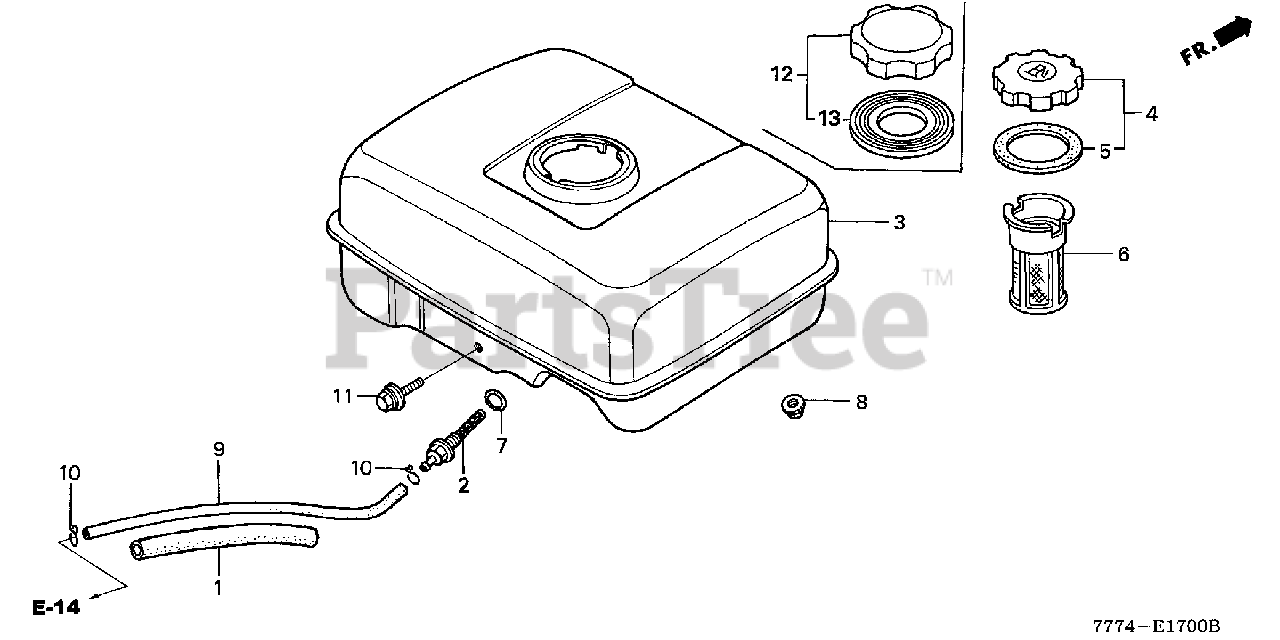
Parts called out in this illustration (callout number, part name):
1	RUBBER, SUPPORTER (107MM)
2	JOINT, FUEL TANK
3	TANK, FUEL *R8* (BRIGHT RED)
3	TANK, FUEL *R280* (POWER RED)
4	CAP, FUEL FILLER
5	GASKET, FUEL FILLER CAP
6	FILTER, FUEL (N/A: USE FILTER 17672-887-791 + FILTER HOLDER 17673-893-000)
7	O-RING (14MM) (ARAI)
8	NUT, FLANGE (6MM)
9	BULK HOSE, FUEL (4.5X3000) (4.5X140)
10	CLIP, TUBE (B8)
11	BOLT, FLANGE (6X29)
11	BOLT, FLANGE (6X30)
